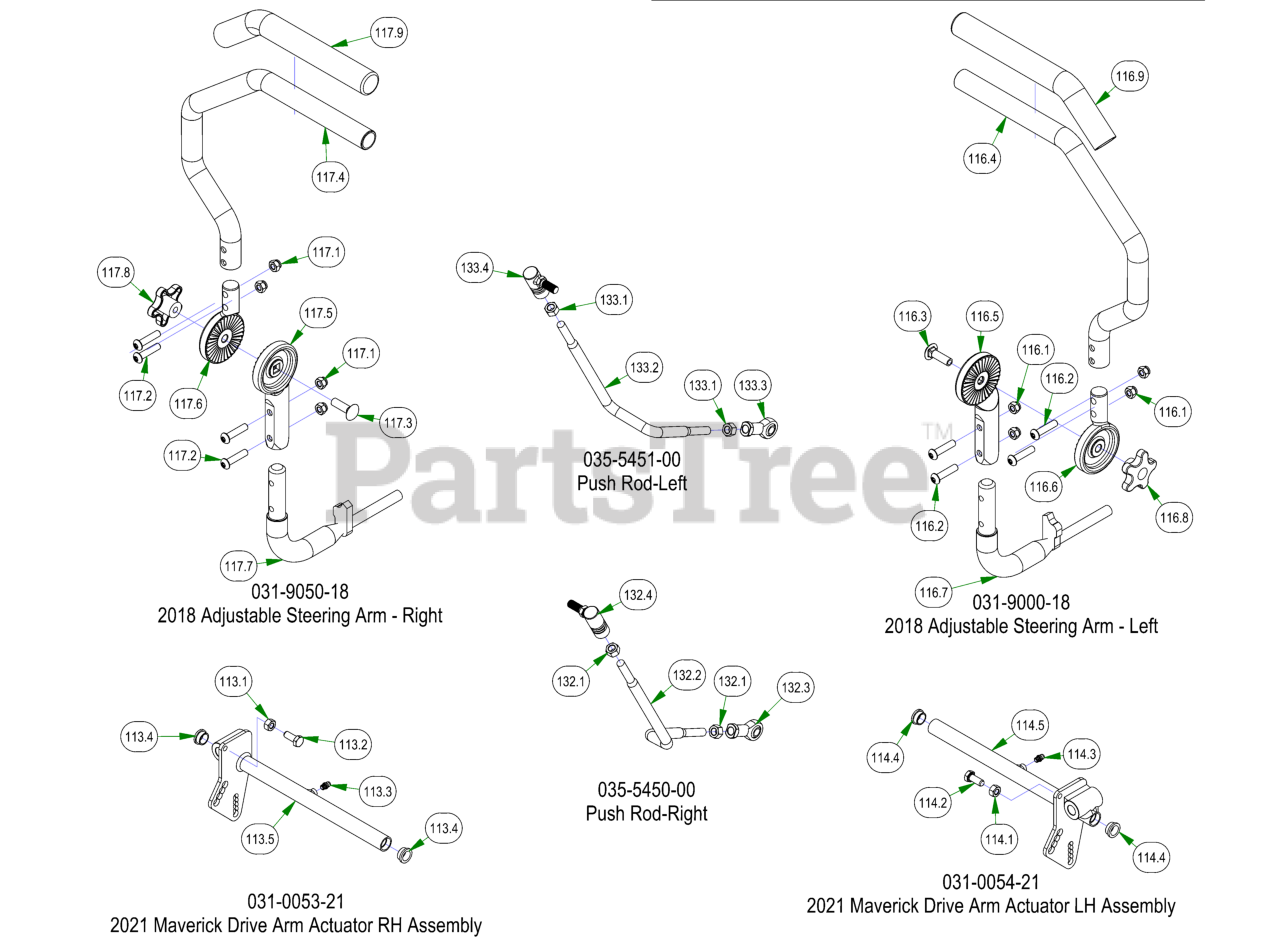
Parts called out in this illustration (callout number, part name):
113	2021 Maverick Drive Arm Actuator RH Assembly
113.1	5/16-18 HEX NUT ZINC
113.2	5/16-18 X 3/4 HEX CAP SCREW (GR.5) ZINC
113.3	1/4" Press in Grease Fitting
113.4	2019 Drive Arm Bushing
113.5	2021 Drive Actuator RH Weldment
114	2021 Maverick Drive Arm Actuator LH Assembly
114.1	5/16-18 HEX NUT ZINC
114.2	5/16-18 X 3/4 HEX CAP SCREW (GR.5) ZINC
114.3	1/4" Press in Grease Fitting
114.4	2019 Drive Arm Bushing
114.5	2021 Drive Actuator LH Weldment
116	2018 Adjustable Steering Arm - Left
116.1	5/16-18 NYL INS L/N ZC
116.2	5/16-18 UNC X 1-3/8" BHCS, TORX DRIVE, GR 5
116.3	3/8-16 X 1-1/4 CARRIAGE BOLT ZINC
116.4	Upper Tube-Adjustable Steering
116.5	2018 Lower Adjuster - Steering Arm- Left
116.6	2018 Upper Adjuster - Steering Arm- Left
116.7	Steering Arm Elbow (Left)
116.8	Black Knob for Adjustable Steering Arm
116.9	Rubber Grip
117	2018 Adjustable Steering Arm - Right
117.1	5/16-18 NYL INS L/N ZC
117.2	5/16-18 UNC X 1-3/8" BHCS, TORX DRIVE, GR 5
117.3	3/8-16 X 1-1/4 CARRIAGE BOLT ZINC
117.4	Upper Tube-Adjustable Steering
117.5	2018 Lower Adjuster - Steering Arm- Right
117.6	2018 Upper Adjuster - Steering Arm- Right
117.7	Steering Arm Elbow (Right)
117.8	Black Knob for Adjustable Steering Arm
117.9	Rubber Grip
132	Push Rod-Right
132.1	3/8" Fine Threaded Jam Nut
132.2	Push Rod RH (Rod Only)
132.3	Spherical Rod End - Outlaw
132.4	Quick Release Ball Joint
133	Push Rod-Left
133.1	3/8" Fine Threaded Jam Nut
133.2	Push Rod LH (Rod Only)
133.3	Spherical Rod End - Outlaw
133.4	Quick Release Ball Joint
